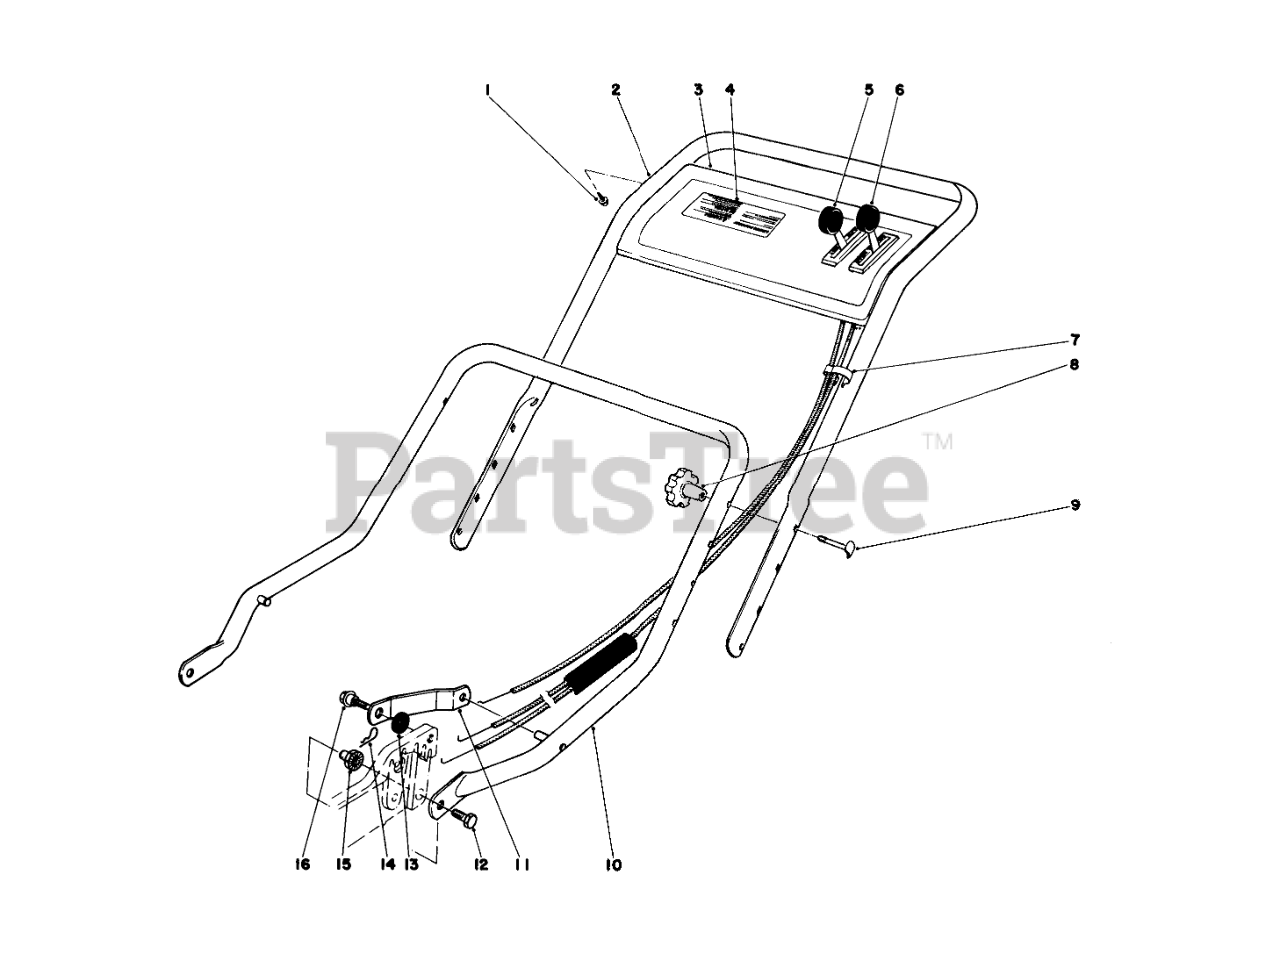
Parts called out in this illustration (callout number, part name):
1	SCREW-HWHTF
2	Upper Handle
3	Control Plate
4	Decal Control Plate
5	Throttle Control
6	Traction Control
7	BOWDEN CLIP
9	HANDLE SCREW
10	Lower Handle
11	HANDLE LATCH
12	SCREW-HH
13	SPACER
14	PIN-COTTER, HAIR
15	HANDLE PIVOT NUT
16	SCREW-SHOULDER
